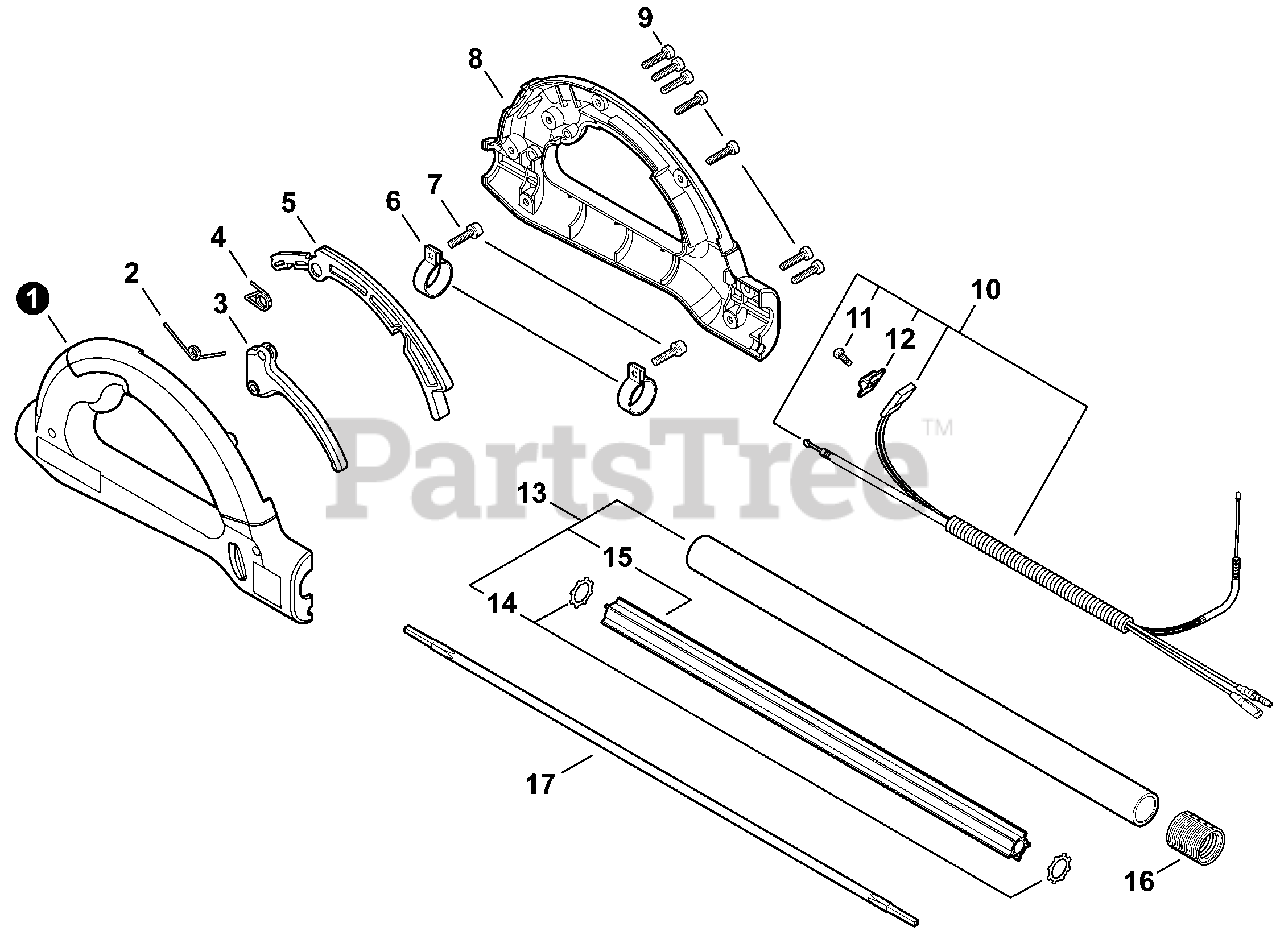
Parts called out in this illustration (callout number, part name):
1	BODY, HANDLE - LEFT
2	SPRING, TORSION
3	TRIGGER, THROTTLE
4	SPRING, TORSION
5	LOCKOUT, THROTTLE
7	BOLT, TORX 5×16
8	BODY, HANDLE - RIGHT
9	BOLT, TORX 5×16
10	CABLE ASSY, CONTROL
11	SCREW 3×10
12	KNOB, SWITCH - ORANGE
13	PIPE, MAIN
16	TUBE, FLEXIBLE
17	DRIVESHAFT - FLEXIBLE
